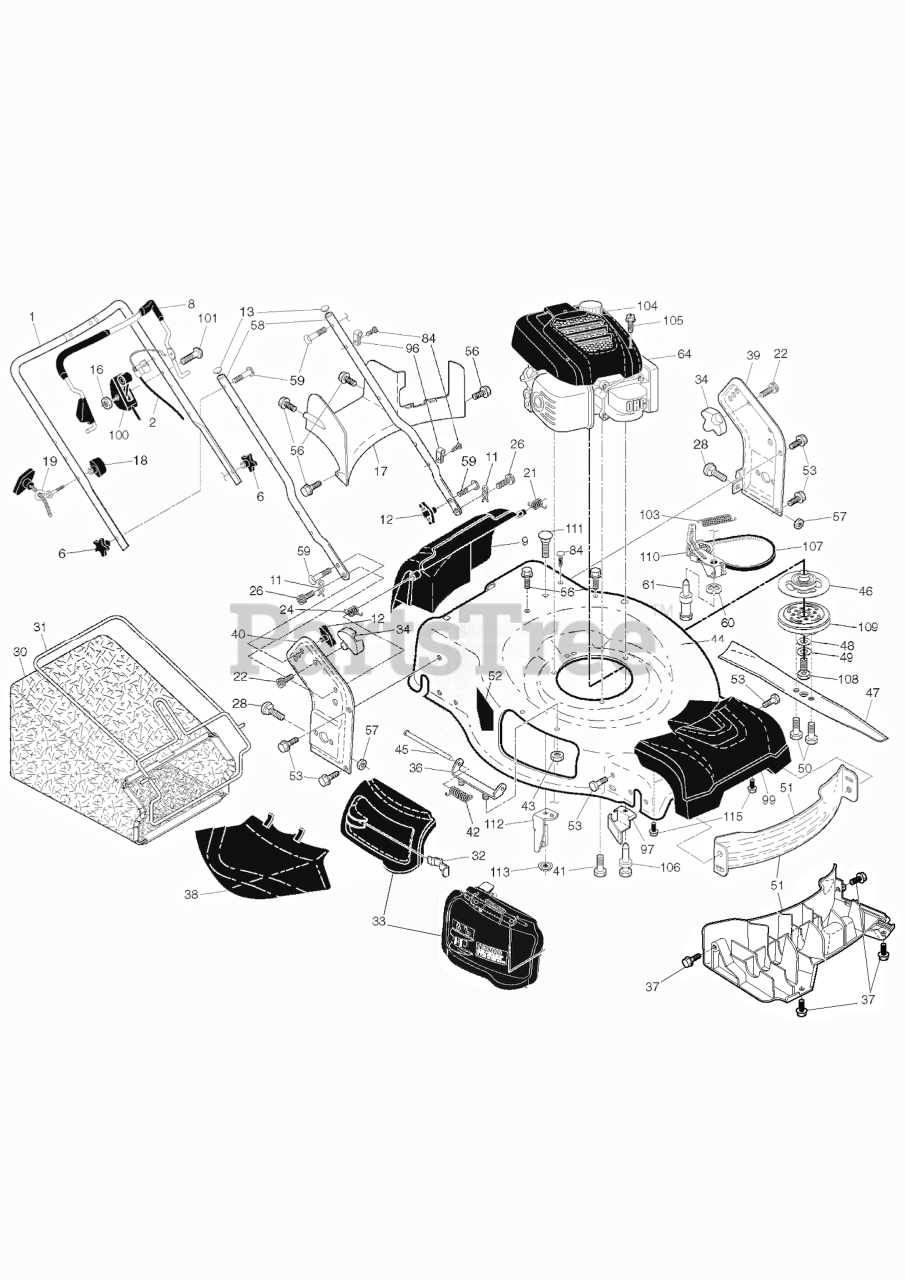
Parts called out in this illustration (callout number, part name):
1	HANDLE.UP.3POS.BS.AW2.GREY
1	HANDLE.UPPER.3.POS.BS.AW2.GREY
2	CABLE.BBC.22+.AW2.BS.ERGO.WALK
6	KNOB.HANDLE.PLASTIC.STAR.BLACK
8	BAIL.ASM.BBC.EN.ERGO.OM.OR/BK
9	DOOR.REAR.ASM.22+.HUSQ.F/RG.CE
11	COTTER.HAIRPIN.DOOR/HANDLE.PIV
12	KNOB, DEFLECTOR
13	PLUG.PLASTIC.7/8".14-20.GAUGE
16	NUT
17	BAFFLE.REAR.22+RGD.AWD.PLASTIC
18	T-KNOB.NEW ROPE GUIDE
19	GUIDE.ROPE.BLK.ZINC.CHROM
21	SPRING.LH.BLACK
22	SCREW.PAN.HEAD.#10
24	SPRING.RH.GRAY
26	SCREW,DOOR/HANDLE.PIVOT
28	BOLT.CARRIAGE.LN.5/16-18X.5/8
28	BOLT
30	GBAG.BA85028ER.GRY/ORG
31	FRAME.GBAG.22+.BLK
32	LATCH.DOOR.ZINC
33	DOOR.MULCH.22 PLUS.HUSQ.GREY
33	DOOR ASSY KIT.MULCH DOOR.CE 22
34	BRACKET.GRASSBAG.ATTACHING.BLK
36	BRACKET.ASM.HINGE.21.FWGD.
37	SCREW.HI-LO.5/16 X.75
37	SCREW.HI-LO. 5/16 X 1.00
38	DEFLECTOR.CLIPPING.22.BLACK
39	BRACKET.ASM.HNDL.LT.22+.GREY
39	BRACKET.ASM.HANDLE.LT.22+.GREY
40	BRACKET.ASM.HANDLE.RT.22+.GREY
40	BRACKET.ASM.HNDL.RT.22+.GREY
41	BOLT 3/8-16X1-1/8
42	SPRING.TORSION
43	NUT.HEX.FLANGE.1/4
43	NUT.FLANGE.1-4-20-SERR
44	HOUSING.22+RG.MC.WO.BBC.668.TR
44	KIT.HSG.22+RG.MC.WO.668.CE SYM
45	ROD.HINGE.21
46	PULLEY.BBC.DRIVING
47	RP.BLADE.22.4N1.BBC.RUST PREV
48	WASHER.CRANK.BOLT
49	LOCKWASHER
50	BOLT.BLADE
51	BAFFLE.FRONT.22+PLASTIC.(2 2)
51	BAFFLE.FRONT.22.PLUS
52	DECAL.INTERNATIONL.CUTFINGER
53	BOLT.5/16HEX.WHS.HD
56	SCREW.HX.13X.750
57	NUT.FLANGE.5/16
58	HANDLE.LOWER.22+BT.2PC.GRY
58	HANDLE.LOWER.22+.BT.GRAY
59	BOLT, HANDLE 5/16-18X1.75
60	E-RING.12MM.SHAFT
61	BOLT.BBC.TENSION.PIVOT
84	FASTENER.PUSH.O.250X0.783
96	CLIP.CABLE.BLK
97	BRACKET.BELT.GUIDE.22+.BZP
99	COVER.ASM.FRONT.HUSQ.22+RGD
99	COVER.ASM.FRONT.SHROUD.HUSQ.
100	CONTROL.THROTTLE.HOND.BBC.58.5
103	SPRING.BRAKE.RESET
104	SHROUD.ASM.HONDA.HUSQVARNA
105	SCREW.SHROUD.HONDA
106	BOLT.BRAKE.RESET.SPRING
107	BELT.COG.BBC
108	SCREW, HEX HD 3/8-24 X 1-3/8
109	HUB.FREE.BBC.ASSEMBLY(2 2MC)
110	ARM.BBC.TNSION.ARM.PULL(2 2MC)
112	BRACKET.CABLE MOUNTING.22+
113	NUT.FLANGE.1-4-20-SERR
115	SCREW.HI-LO. 5/16 X 1.00
